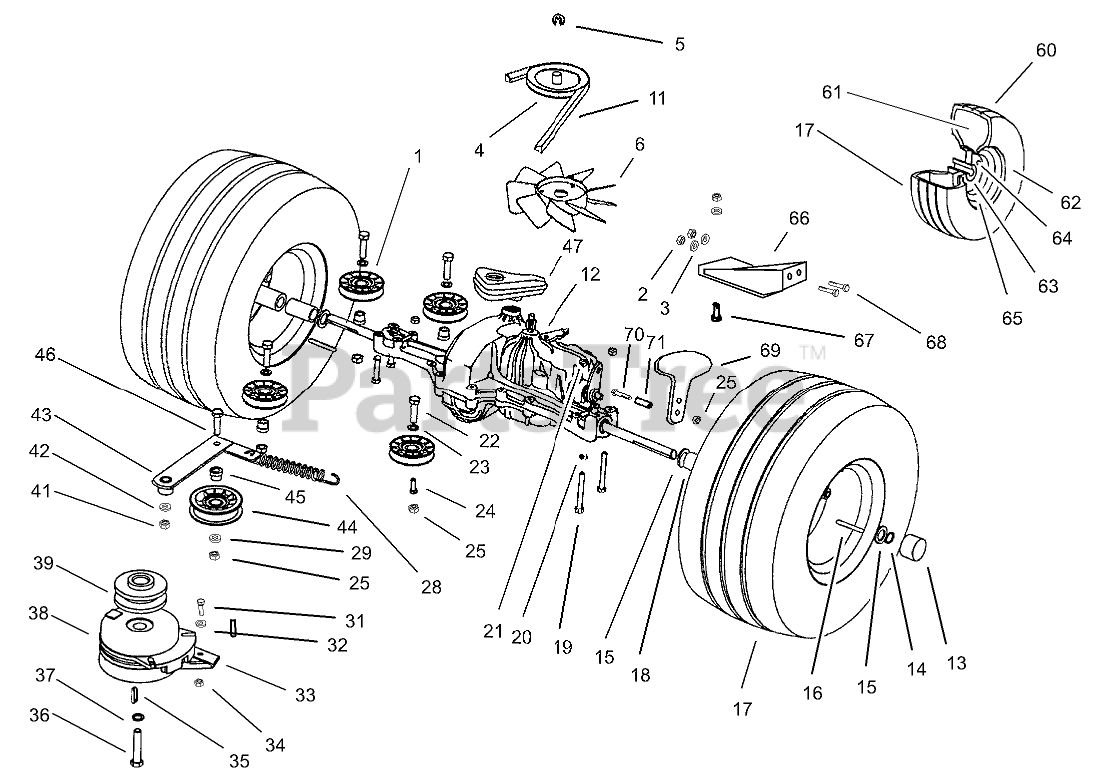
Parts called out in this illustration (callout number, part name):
1	PULLEY-IDLER
2	NUT-LOCK, NI
3	WASHER-PLAIN
4	PULLEY-TRANSMISSION
5	E-RING
6	FAN-TRANSMISSION
11	V-BELT-TRACTION
12	TRANSMISSION
13	CAP-HUB
14	CLIP-SPRING
15	WASHER
16	KEY-SQUARE
17	REAR TIRE ASM
18	SPACER-AXLE
19	CAPSCREW
20	WASHER-PLAIN
21	NUT-LOCK, NI
22	SCREW-HH
23	WASHER-FLAT
24	BUSHING-IDLER
25	NUT-LOCK, NI
28	SPRING
29	WASHER-FLAT
31	SCREW-HH
32	WASHER-PLAIN
33	RETAINER
34	NUT-LOCK, NI
35	KEY-SQUARE
36	SCREW-HH
37	WASHER-SPRING, BELLEVILLE
38	CLUTCH-ELECTRIC
39	PULLEY-ENGINE
41	NUT-LOCK, NI
42	WASHER-PLAIN
43	ARM-IDLER
44	PULLEY-IDLER
45	BUSHING-IDLER
46	SCREW-HH
47	RESERVOIR TANK ASM WITH CAP
60	TIRE-TURF SAVER 4 PLY
62	WHEEL ASM
63	HUB-WHEEL
64	NUT-WHEEL
65	VALVE-TYRE
66	STABILIZER-20" WHEELS
67	SCREW-HEX HD
68	SCREW-HH
69	ARM-CRUISE CONTROL
70	SCREW-HH
71	SLEEVE
